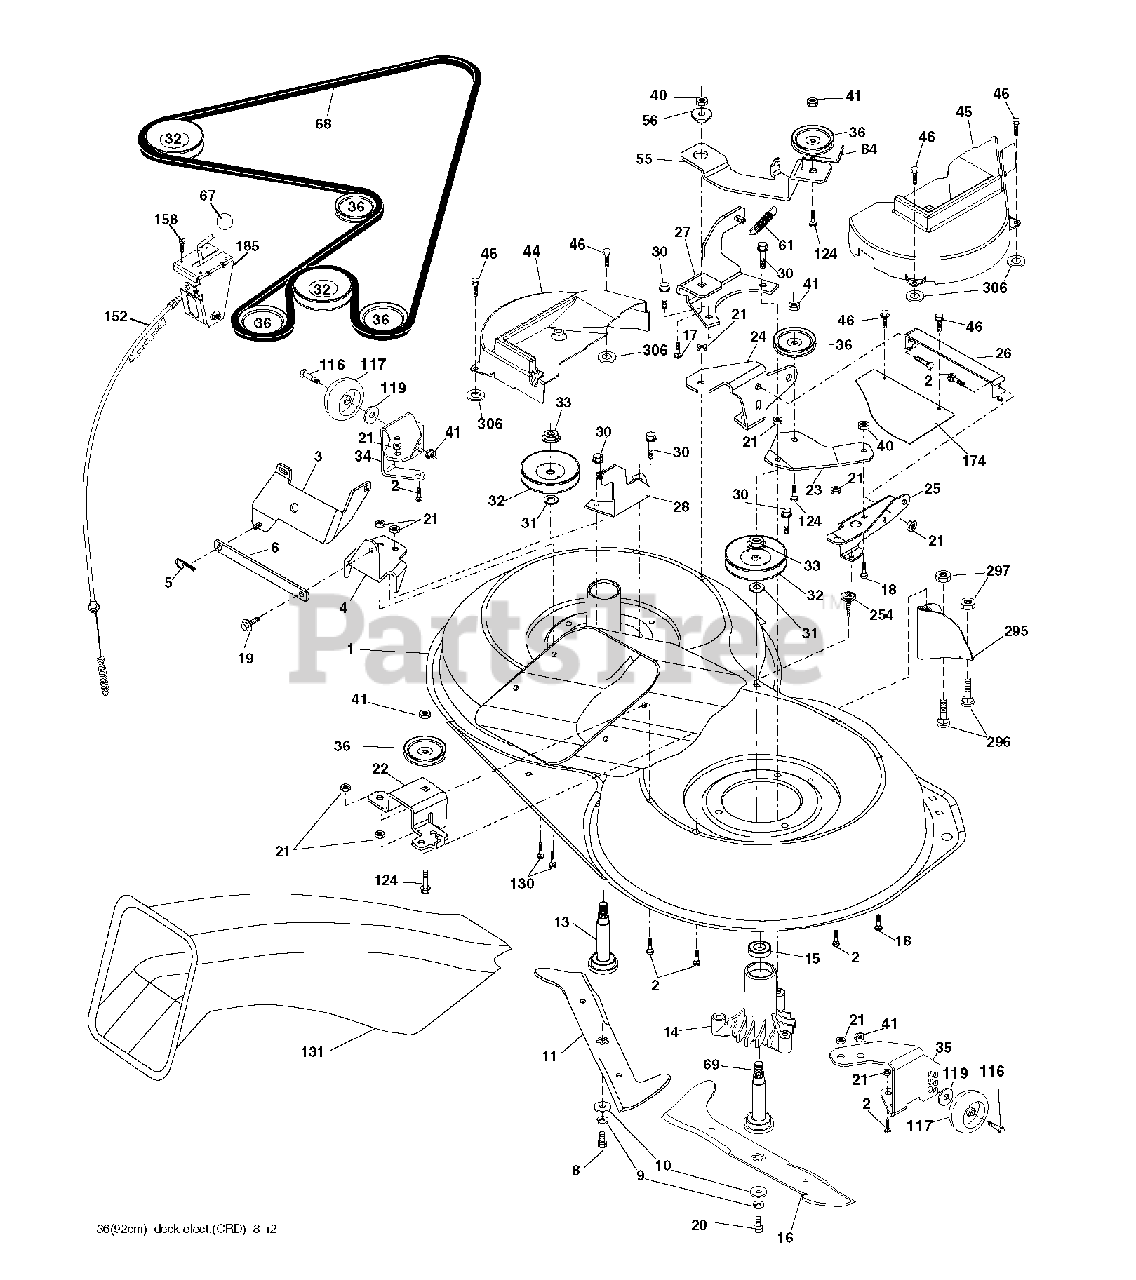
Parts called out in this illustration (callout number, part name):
2	BOLT
3	BRACKET
5	RETAINER-SPRNG RB
6	BAR SWAY
9	LOCKWASHER
10	WASHER.BLADE
13	SHAFT ASM VENT
14	HSG MANDREL
17	BOLT.3/8-14X1.25
19	BOLT SHD 5/16-18
21	LOCKNUT
24	BRACKET
25	BRACKET
28	BRACKET
30	SCREW, WASHER HEAD
31	WASHER.SPACER.MANDREL
32	PULLEY MANDREL
33	NUT.FLANGE.LOCK.TOP
36	PULLEY.IDLER.4.25
40	LOCKNUT
41	NUT LOCK FLG 3/8-16 UNC
46	SCREW.1/4-20X5/8
56	SPACER.RETAINER.MOWER
67	KNOB T (3/8 HOLE)
69	SHAFT.ASM.W/LWR.BRG.RH.THREAD
84	KEEPER, BELT IDLER
116	BOLT.SHOULDER.3/8-16X3-5/8
117	WHEEL. GUAGE RALLY
124	BOLT.3/8-16X1.50
131	CHUTE BAGGER
158	SCREW
185	HEAD ASM. CABLE CLUTCH
254	SCREW 3/8-16X1
296	BOLT
297	NUT CENTERLOCK
306	PALNUT 1/4
